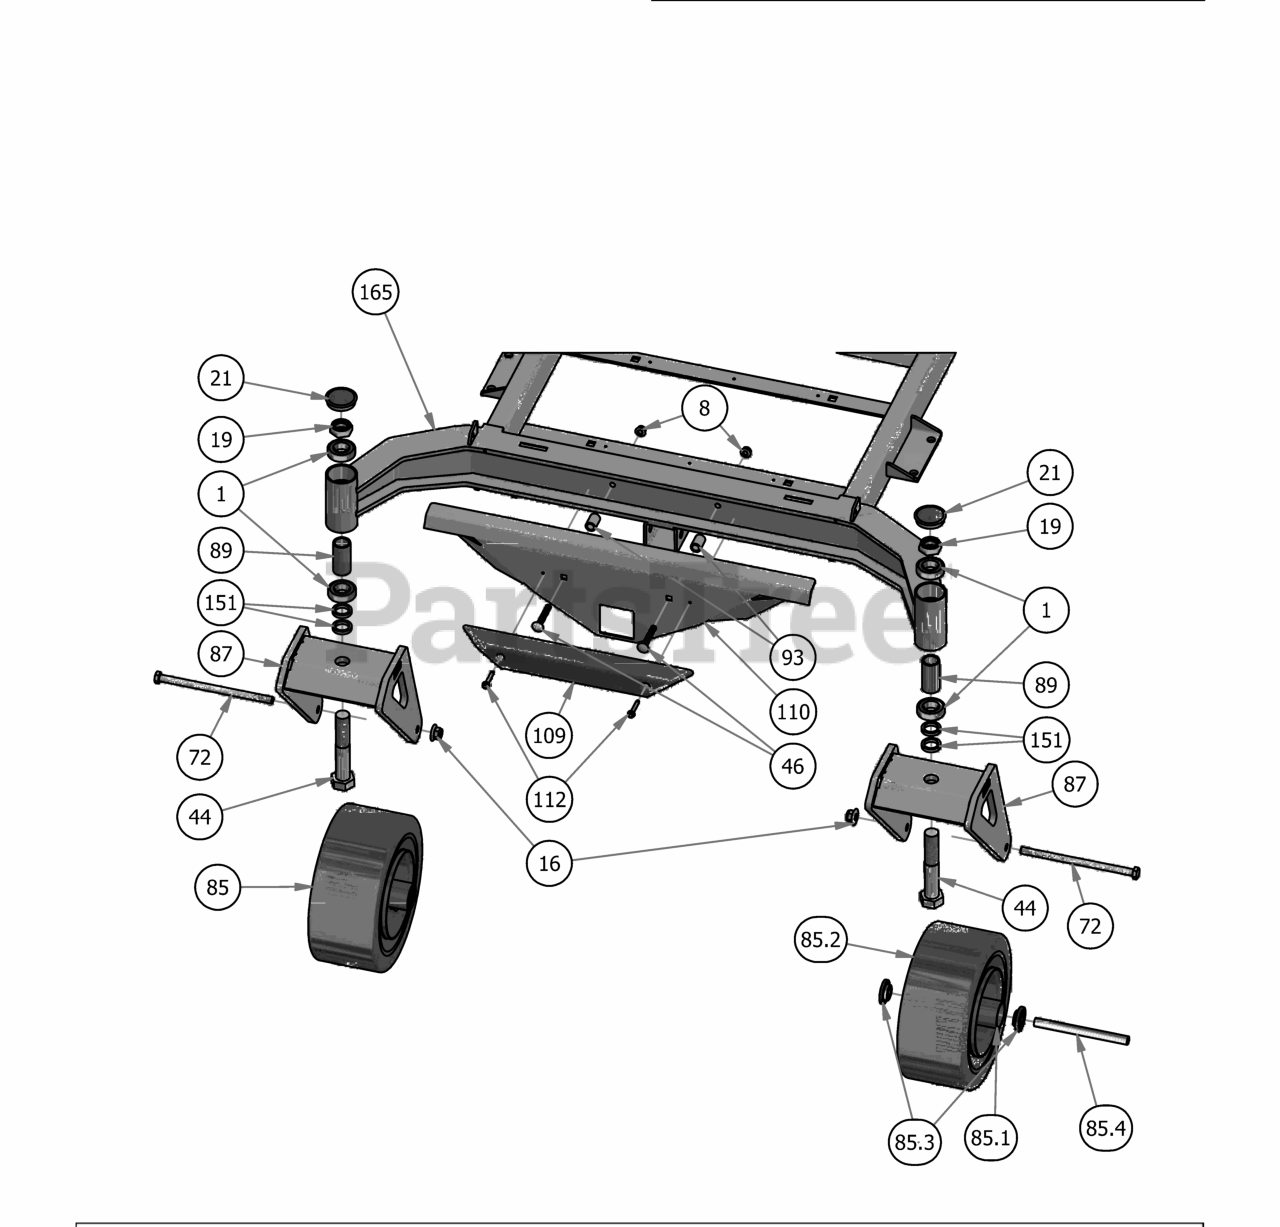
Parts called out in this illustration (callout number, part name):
1	Caster Bearing 2016 - 1641 Bearing
8	3/8" Nylock Flange Nut
16	1/2-13 Nylon Flange Nut
19	1" Fine Thread 1/2 Nylock Nut
21	2017 Bearing Cover
44	1-14 x 5.5 Hex Bolt Grade 8 Zinc Yellow
46	3/8" x 2 1/2" Carriage Bolt
72	1/2" x 9" GR 5 Hex Bolt
85	Tire and black wheel assembly
85.1	Black Front Tire Rim
85.2	13 x 6.50 - 6 Tire
85.3	1-3/4" Bearing-Large Bore Front Rim
85.4	Front Wheel Spanner
87	2019 Rebel Front Fork - Weldment
89	2016 Front Bearing Spacer
109	2017 XP Bumper
110	2019 Outlaw Rigid Front Bumper Plate
112	1/4" x 1 1/2" Self Tapping Screw
151	Spacer, 1x1.375x.25
165	2019 Rigid Frame
